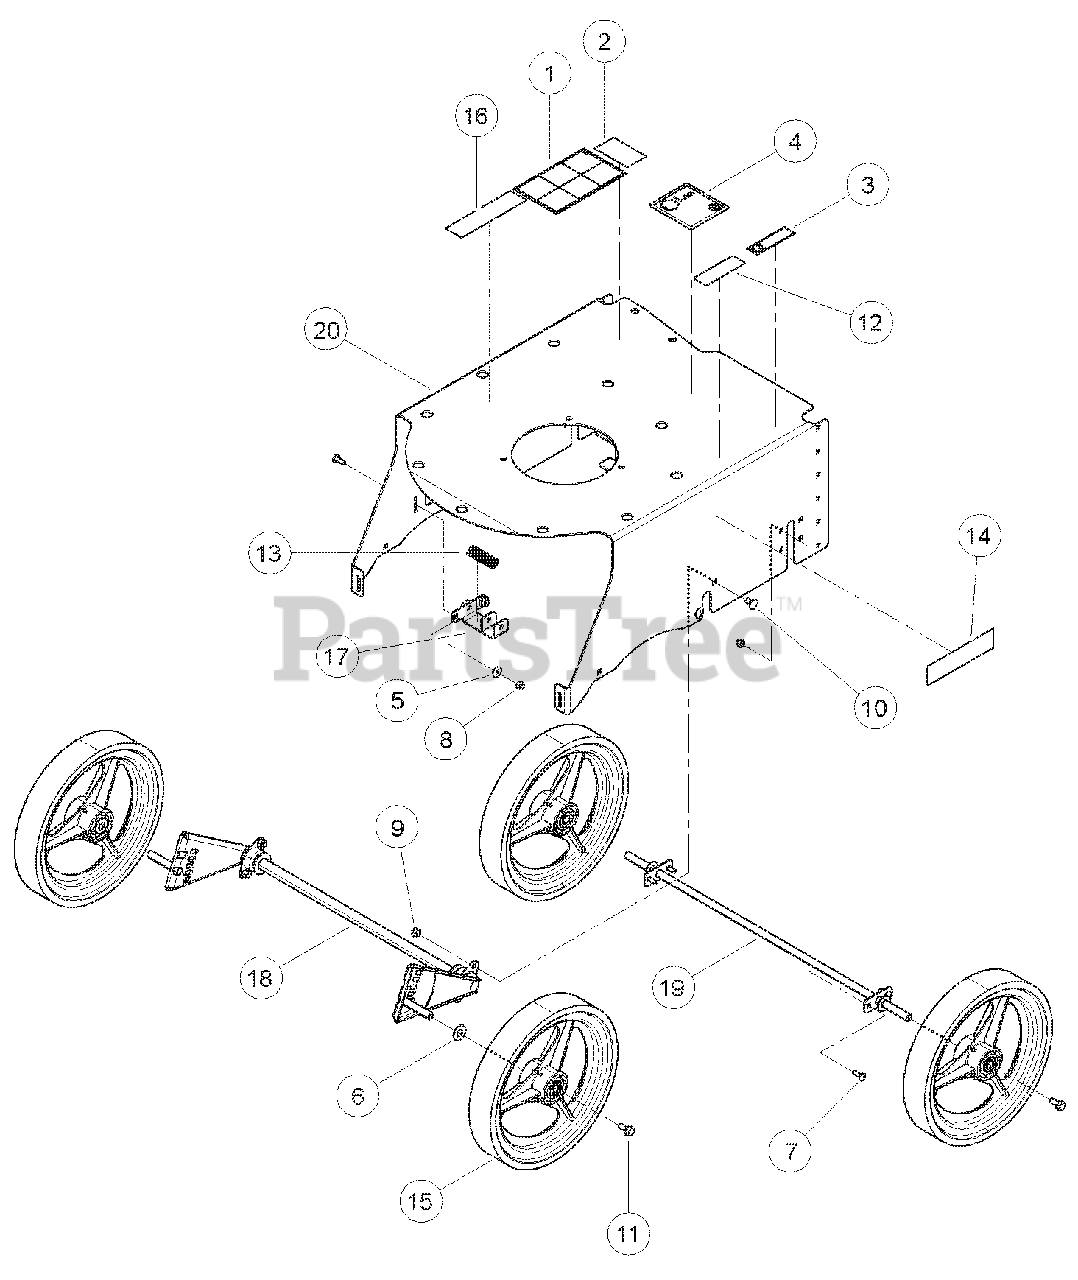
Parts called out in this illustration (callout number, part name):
1	DECAL, OPERATING INSTRUCTIONS ISO
2	DECAL, DANGER
3	DECAL, 6HP PUSH BEARVAC INFORMATION
4	DECAL, 97 DB
5	WASHER, 1/4 FLAT ZP
6	WASHER, 1/2 SAE FLAT ZP
7	BOLT, 1/4 X 3/4 CRG GR5 ZP
8	NUT, 1/4 NE NYLOCK ZP
9	NUT, 5/16 NE NYLOCK ZP
10	BOLT, 5/16 X 5/8 CRG GR5 ZP
11	BOLT, 5/16 X 3/4 THREAD CUTTING
12	DECAL, SERIAL NUMBER
13	SPRING, LC-072J065 COMPRESSION
14	DECAL, ECHO BEARCAT
14	DECAL, CRARY BEARCAT
15	WHEEL ASSEMBLY, BEARVAC PUSH
16	DECAL, MODEL WV190
17	WELDMENT, BEARVAC HEIGHT ADJUST
18	WELDMENT, AXLE PIVOT
19	WELDMENT, AXLE BEARVAC PUSH
20	SUPPORT, BEARVAC FRAME
